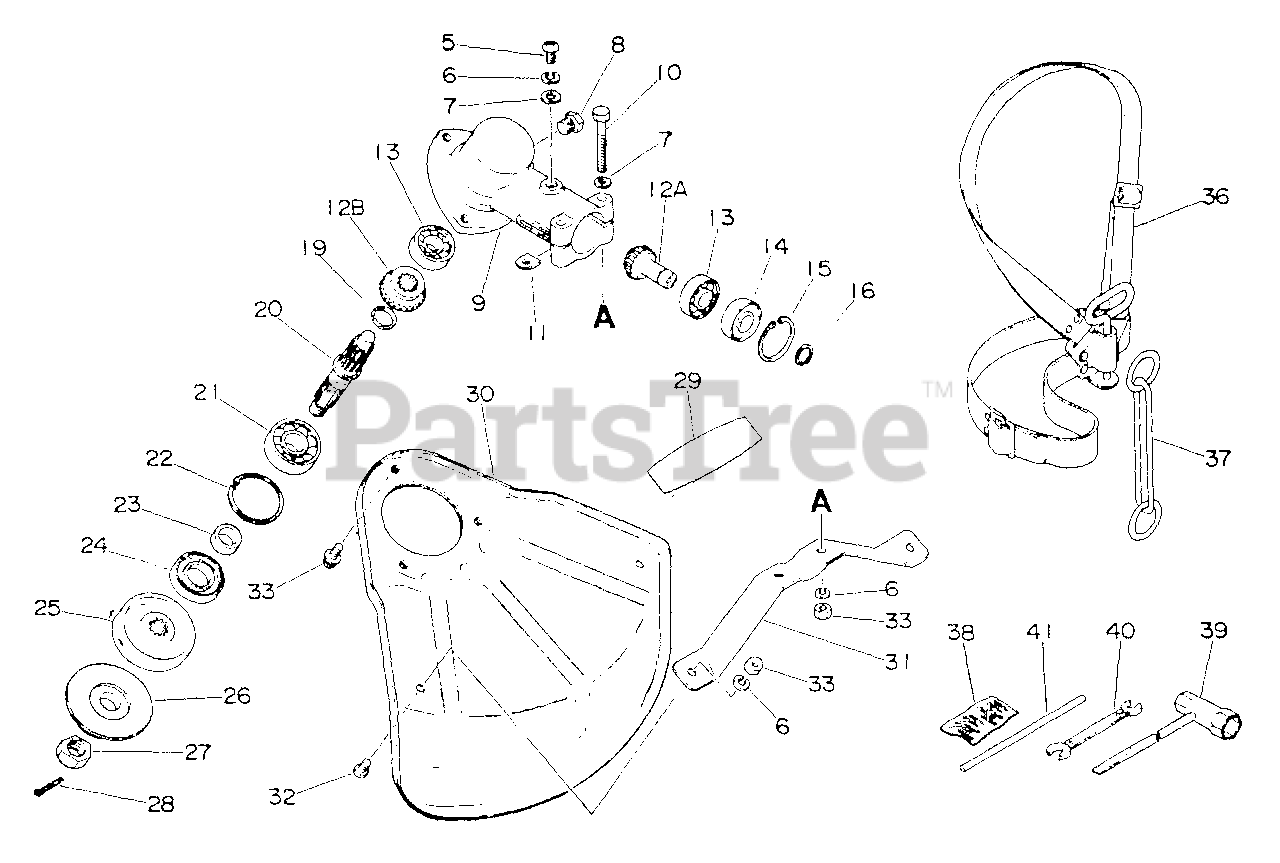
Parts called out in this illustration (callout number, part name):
5	SCREW - 5X10
6	LOCKWASHER - 5
7	WASHER - 5
8	BOLT - 8X8
9	CASE, GEAR
10	BOLT - 5X35
12	GEAR SET
12A	GEAR SET
12B	GEAR SET
13	BEARING, BALL - 609
14	BEARING, BALL - 609
15	RING, RETAINING - 25
16	RING, RETAINING
19	RING, RETAINING - 12
20	GEAR - SHAFT
21	BEARING, BALL - 6201
22	RING, RETAINING - 32
24	SEAL, OIL
25	ADAPTOR, BLADE - UPPER
26	ADAPTOR, BLADE - LOWER
27	NUT - 10 -- LEFT HAND
28	PIN, SPLIT - 2X22
29	LABEL - ECHO
30	SHIELD ASSY - PLASTIC
31	BRACKET, SHIELD
32	SCREW - 5X8
36	SHOULDER STRAP ASSY
38	PIN, SPLIT - 2X22
39	T-WRENCH
40	SPANNER - 8X10mm
41	LOCKING TOOL
